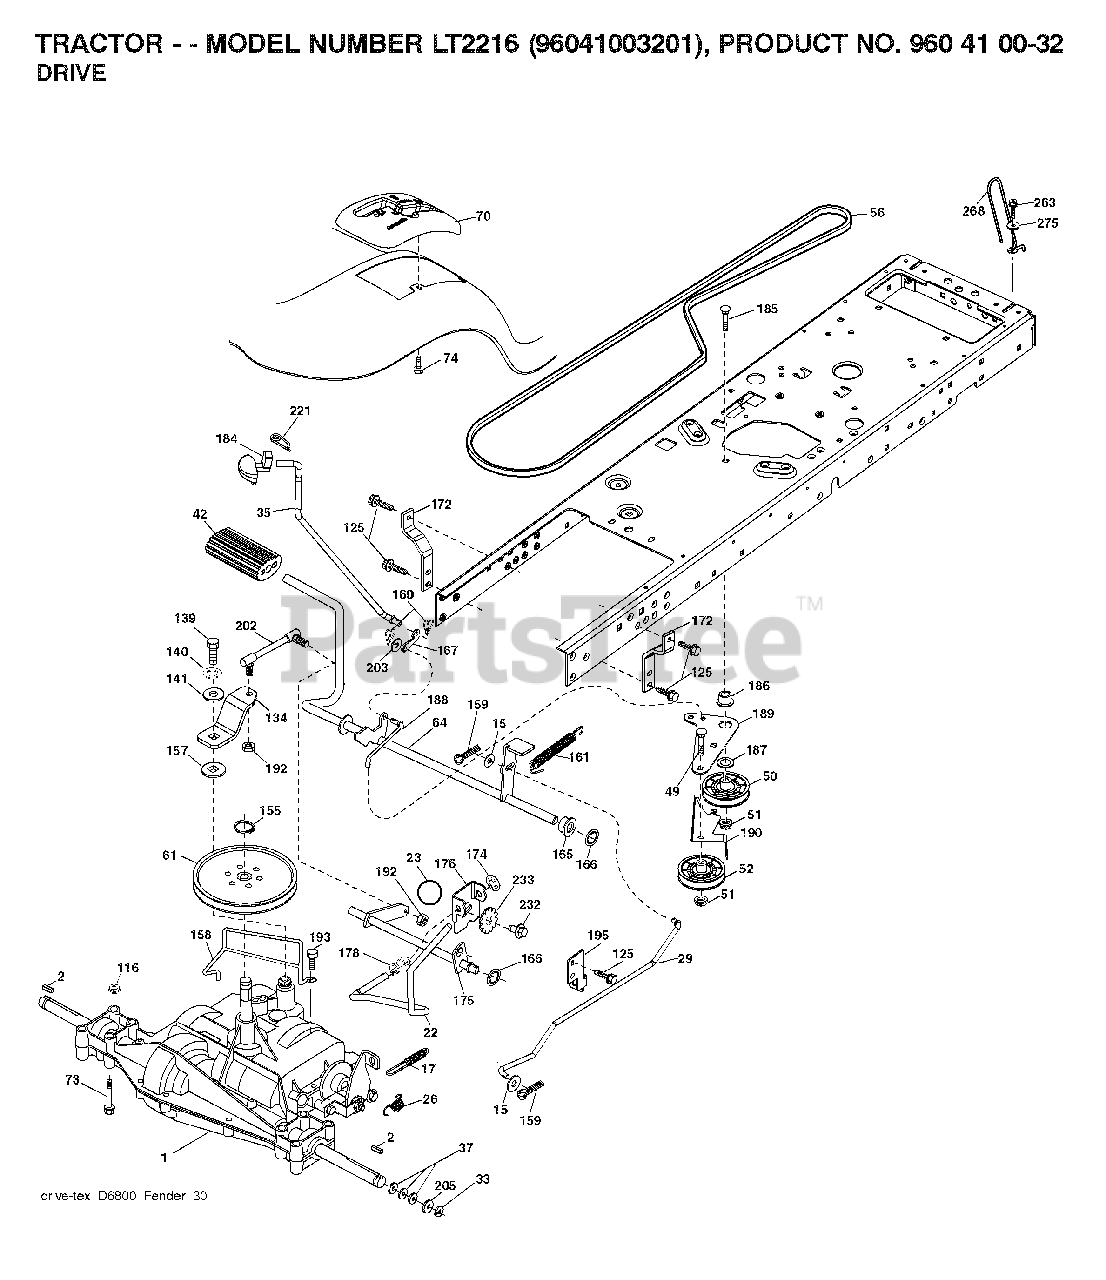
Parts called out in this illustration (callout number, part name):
2	SQUARE KEY
17	SPRING.BRAKE.PEERLESS.TEX
22	ROD.SHIFT.FENDER.TLT.2006
23	KNOB.DUCKHEAD.1/2
26	SPRING.BRAKE.RTN.GR.DR
29	ROD.BRAKE.PEERLESS
33	E-RING LT
35	ROD.BRAKE.PARKING.LT.T
42	PEDAL COVER T
49	BOLT
50	IDLER.FLAT.910.OFFSET
51	NUT LOCK FLG 3/8-16 UNC
52	IDLER.V-GROOVE.910.OFFSET
56	V-BELT.TRACTOR.DRIVE.P
61	PULLEY TRANS
64	SHAFT.ASM.PEDAL.BRAKE.
70	CONSOLE.SHIFT.
74	SCREW.HI-LO.CONSOLE
116	NUT LOCK HEX FLANGE 5/16-18
125	SCREW
134	ARM.SHIFT.
139	BOLT 1/4-28X3/4
140	LOCKWASHER
141	WASHER LT
148	SCREW, 3/8-16X3/4
155	RETAINING RING LT
157	WASH-SHFT PLT LT
158	KEEPER.PMS.18/20.D4365
159	COTTER PIN
160	RETAINER CLIP
161	SPRING.RETURN.CLUTCH.2006
162	SPACER.TRANSAXLE.18&22
165	BUSHING.SHAFT.BRAKE.HAND
166	NUT.PUSH.625.2006
167	LATCH.BRAKE.SPRING
172	STRAP.TRQ.LH.GEAR.DRIV
174	NUT.PUSH.500.2006
175	SHAFT.ASM.SHIFT.
176	ARM.CLEVIS.ROD.SHIFT
178	SPRING.SHIFT.GT2006
186	SPACER.RETAINER
187	WASHER 12/32X2X10GA
188	LINK.CLUTCH.GROUND.DRIVE
189	BELLCRANK.GROUND.DRIVE.TEX.
190	KEEPER.BELLCRANK.DRIVE
192	NUT LOCK CENTER 1/4 -28 FNTHD
193	SCREW 5/16"
195	BRKT.ROD.BRAKE.PEERLES
202	LINK.TRANSAXLE.
203	WASHER
221	RETAINER.SPRING.CLIP.H
225	BOLT.HEX.FLNG.5/16-18X3.75
226	BOLT FIN HEX 7/16-14 X 1
227	WASHER SERRATED
275	WASHER
